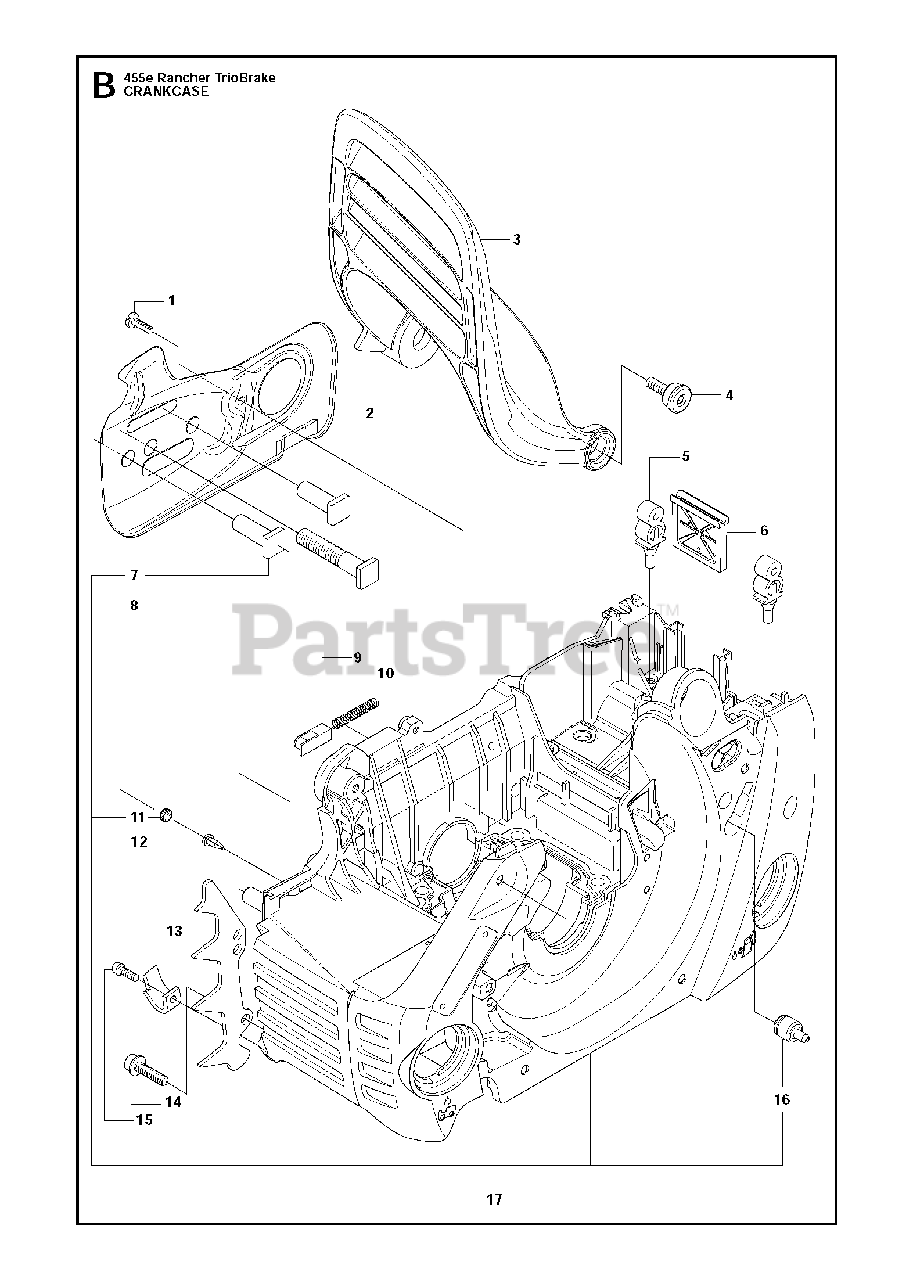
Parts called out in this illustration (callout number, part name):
3	HAND GUARD
4	SCREW, HAND GUARD
7	GUIDE BOLT (X2)
8	BOLT
10	LOCK SPRING
11	PLUG
12	VALVE-CHECK (DUCKBILL)
13	FELLING DOG
14	SCREW
15	CHAIN CATCHER
16	FUEL TANK VENT
17	CRANKCASE ASSY
